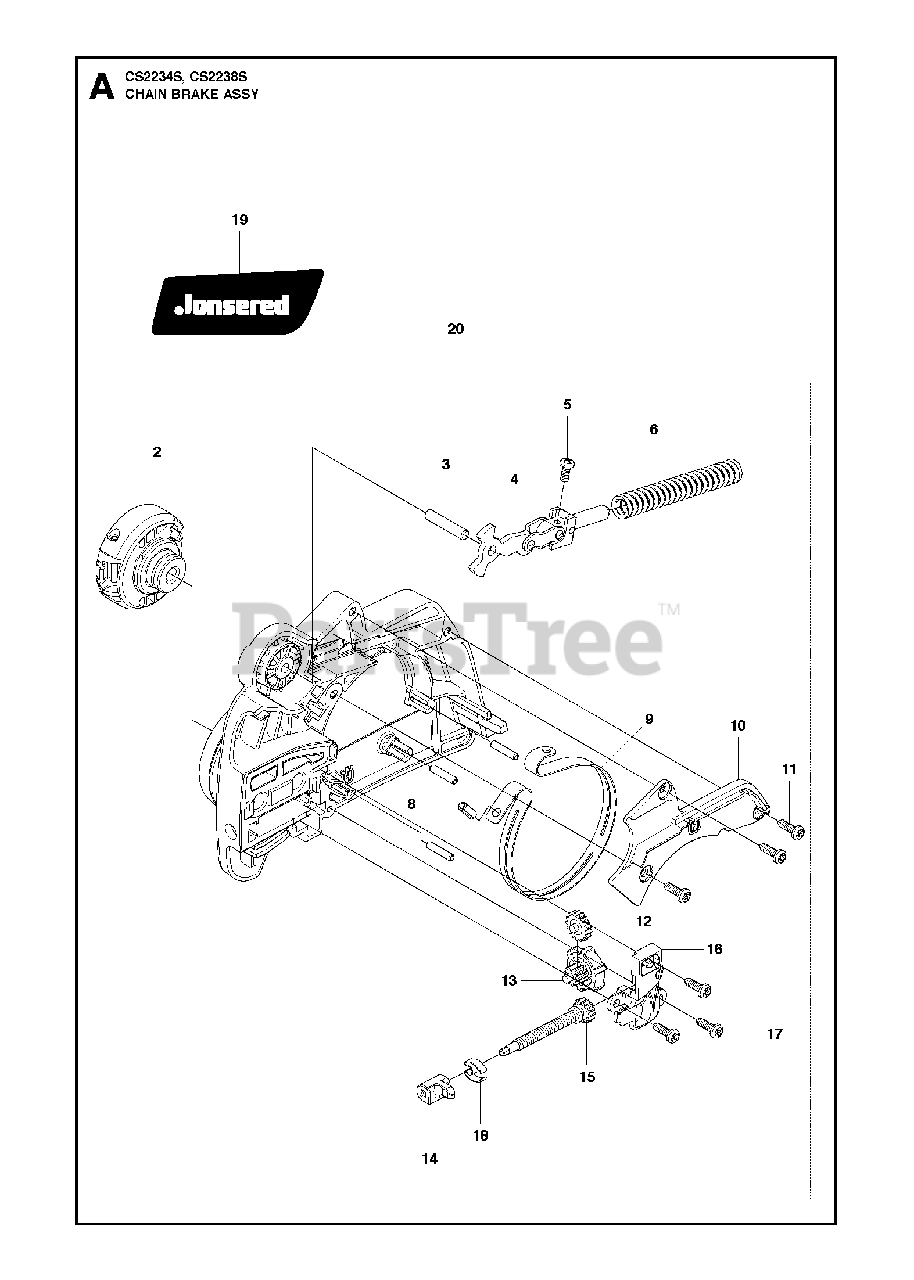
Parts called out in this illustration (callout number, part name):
2	KNOB
3	PIN
4	FRONT LINK ASSY
5	SCREW
6	SPRING
8	PIN
9	BRAKE BAND
11	SCREW 6-19X.437
12	GEAR IDLER
13	ASSY THUMB WHEEL BLACK
14	PIN BAR ADJUSTING EZT
15	SCREW
17	SCREW 6-19X.437
18	CLIP
